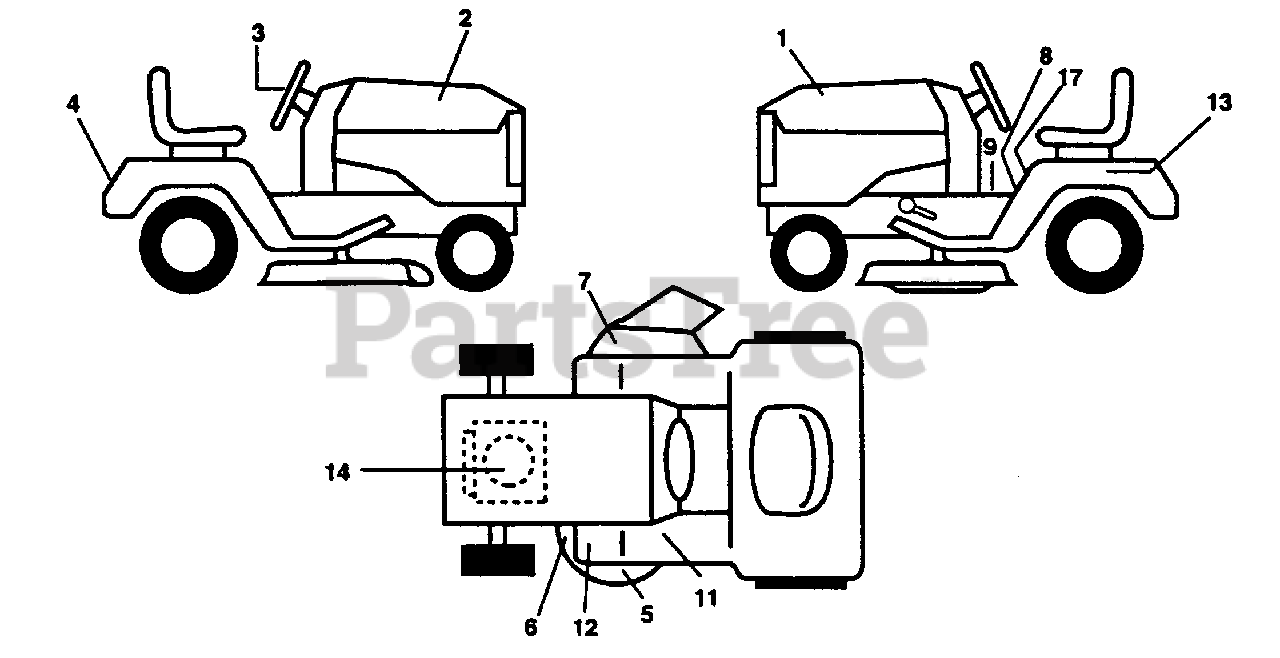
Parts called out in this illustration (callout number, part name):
1	Decal Hood LH 15/42 Hyd Poul P
2	Decal Hood RH 15/42 Hyd Poul P
3	Decal Insert Strg Whl
5	Decal Enviro Deck Yellow
6	Decal, V-Belt Sch 38"/42" LT
7	Decal Warning MULT-LANGUAGE
8	Decal Dash Instructions Operating Eng/Fr
9	Decal Sdl Cold Start Hydro Eng/Fr
11	Pad Footrest Ribbed LT/YT/GT
12	Decal Clutch/brake Eng/Fr/Ger/Du
13	Decal Caution Battery Fr/Ger
14	Decal, Engine B&S 15 HP Diamond Plus
17	Decal Caution Fender Eng/Fr
